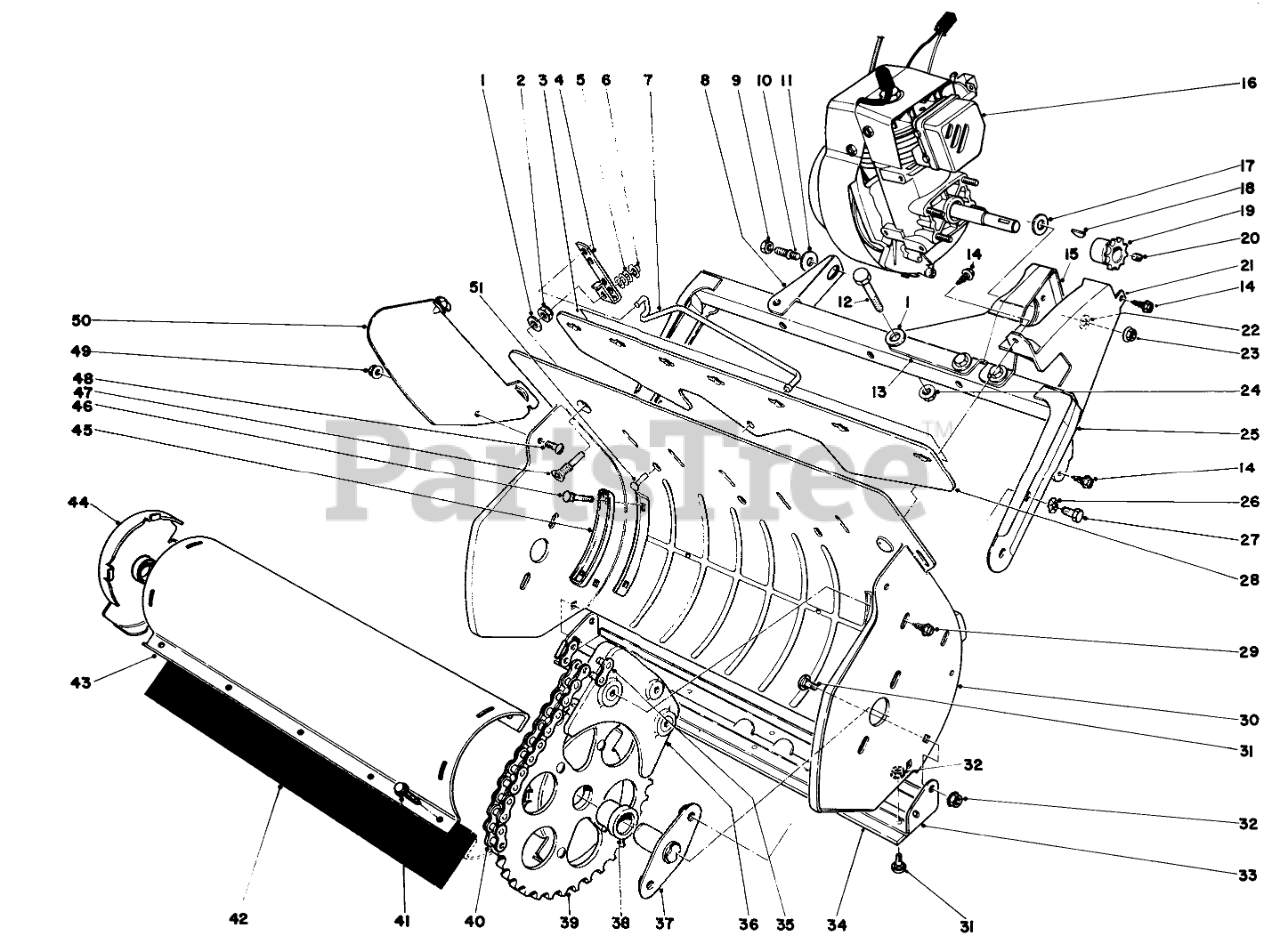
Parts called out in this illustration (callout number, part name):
1	WASHER-FLAT
2	Locknut
3	Decal-Warning
4	Bracket Vane Adjustment
5	WASHER-FLAT
6	NUT-SPEED
7	Linkage Vane Adj.
8	Frame Bracket
9	NUT-LOCK, CONE
11	GRILLE HINGE SPACER
12	SCREW-HH
13	Engine Bracket Internal
14	SCREW-HWHTF
15	Engine Bracket External
16	Engine
17	WASHER-PLAIN
18	KEY-WOODRUFF
19	SPROCKET
20	SCREW-HSH
21	Chain Guard
22	Lockwasher
23	NUT-HF
24	NUT-LOCK, HHF
25	Frame
26	Washer
27	SCREW-HH
28	Vane Mount (Incl. Ref. #3)
29	SCREW-HWHTF
30	Housing
31	SCREW-CARR
32	NUT-KEPS
33	Scraper Assembly (Incl. Ref. #31-32 & 34)
34	SCRAPER
35	LINK-CONNECTING, NO. 35
36	Stripper
37	ROTOR SHAFT ASM
38	ROTOR BUSHING
39	End Cap Assembly L.H. (Incl. Ref. #38)
40	ROLLER CHAIN
41	Screw
42	ROTOR BLADE
43	ROTOR SHELL
44	End Cap Assembly R.H. (Incl. Ref. #38)
45	Handle Plate
46	SCREW-CARR
47	Screw
48	SCREW-PTH
49	NUT-LOCK, FLANGE
50	Vane
51	Pop Pivot
